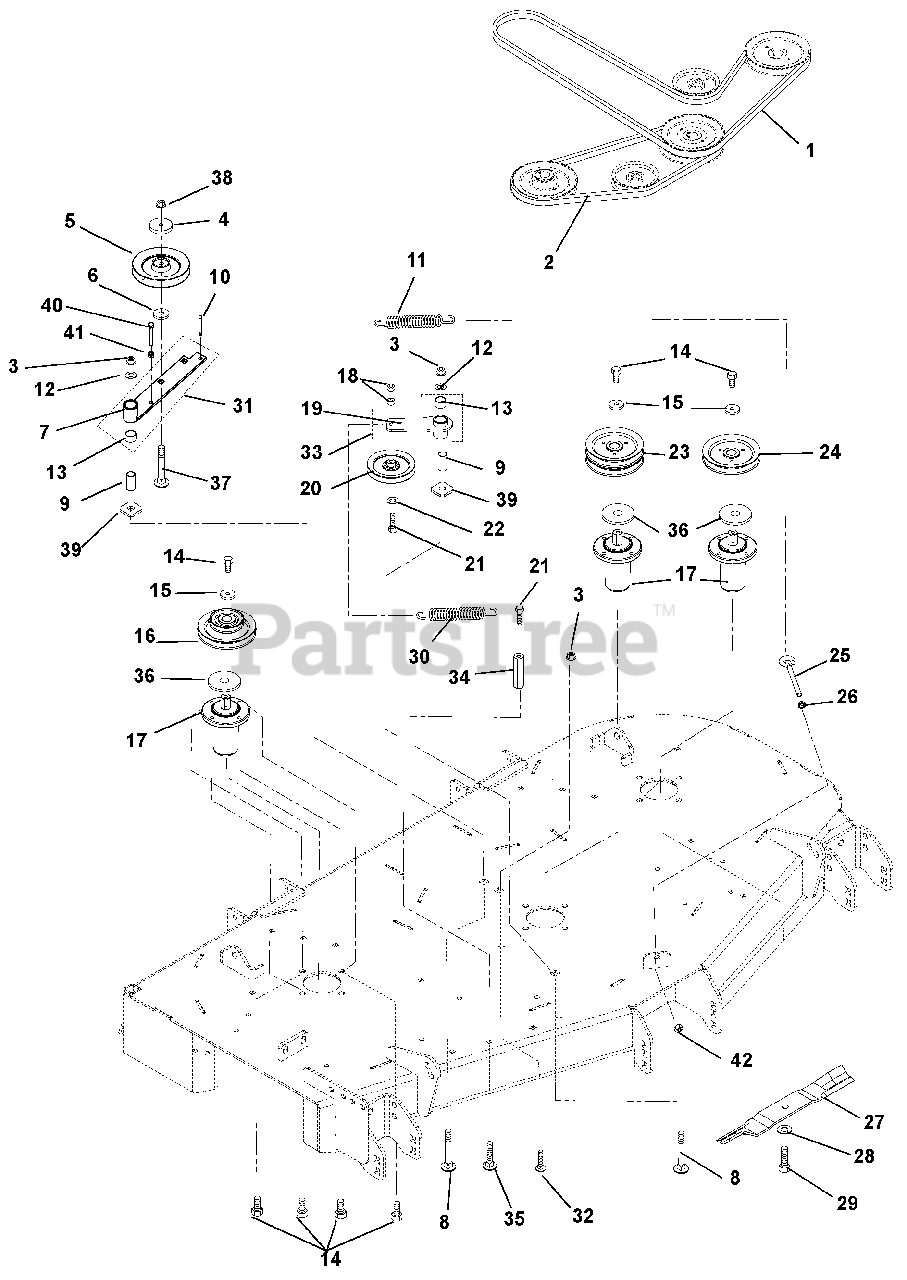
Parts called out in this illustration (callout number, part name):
1	Belt, 120.50" Long, PTO Drive Hex (992212)
2	V-Belt, 56" Long Cog B-Section (992212)
3	Nut, .50-13 Nyloc Flange
4	Cap, Idler Bearing Sealing
5	Sheave, .50"ID x 6.00"OD V-Idler
6	Bushing, Spacer .502 x .997 x .50
7	Weldment, Idler Arm
8	Bolt, Round Head Square Neck .50-13 x 3.50
9	Bushing, Spacer .502 x .997 x 2.03
10	Bolt, Shoulder .38-16 x .30 Hex
11	Spring, Extension
12	Washer, Flat Steel .563 x 1.38 x .109
13	Bushing, 1.00 x 1.125 x 1.936
14	Bolt, Hex .38-16 x 1.00
15	Washer, Flat Steel .406 x 1.50 x .245
16	Sheave, Double, 1" ID x 6" OD and 3.50" OD (992212)
17	Spindle Assembly (992213)
18	Nut, Locking Center .38-16
19	Weldment, Idler Arm
20	Assembly, V-Idler 5.00 O.D.
21	Bolt, Hex .38-16 x 2.25
22	Washer, Flat Steel .406 x .812 x .065
23	Sheave, Double 1" ID x 6.00" OD (992212)
24	Sheave, Single 1" ID x 6.00" OD (992212)
25	Bolt, .38-16 x 5.50 .62 Diameter Eye
26	Nut, Hex, Jam .375-16
27	Blade, 18.00" Mower (HI-LIFT) (992212)
28	Washer, Bellville .63 x 1.625 x.14
29	Bolt, Hex .62-18 x 1.75 Grade 8
30	Spring, Extension
31	Assembly, PTO Idler Pivot Arm (Includes item # 7 and item # 13)
32	Bolt, Round Head Square Neck .50-13 x 1.5, Full Thread, Grade 5
33	Assembly, Idler Pivot Arm (Includes item # 13 and item # 19 )
34	Nut, Coupling .375-16 x 1.75
35	Bolt, Round Head Square Neck .38-16 x 1.00
36	Retainer, Grease
37	Bolt, Round Head Square Neck .50-13 x 3.00 Grade 5
38	Nut, Locking Center .50-13
39	Washer, Flat .640 x 1.75 x .250
40	Bolt, Hex .38-16 x 2.75
41	Nut, Hex .38-16
42	Nut, Locking Center Jam .375-16
